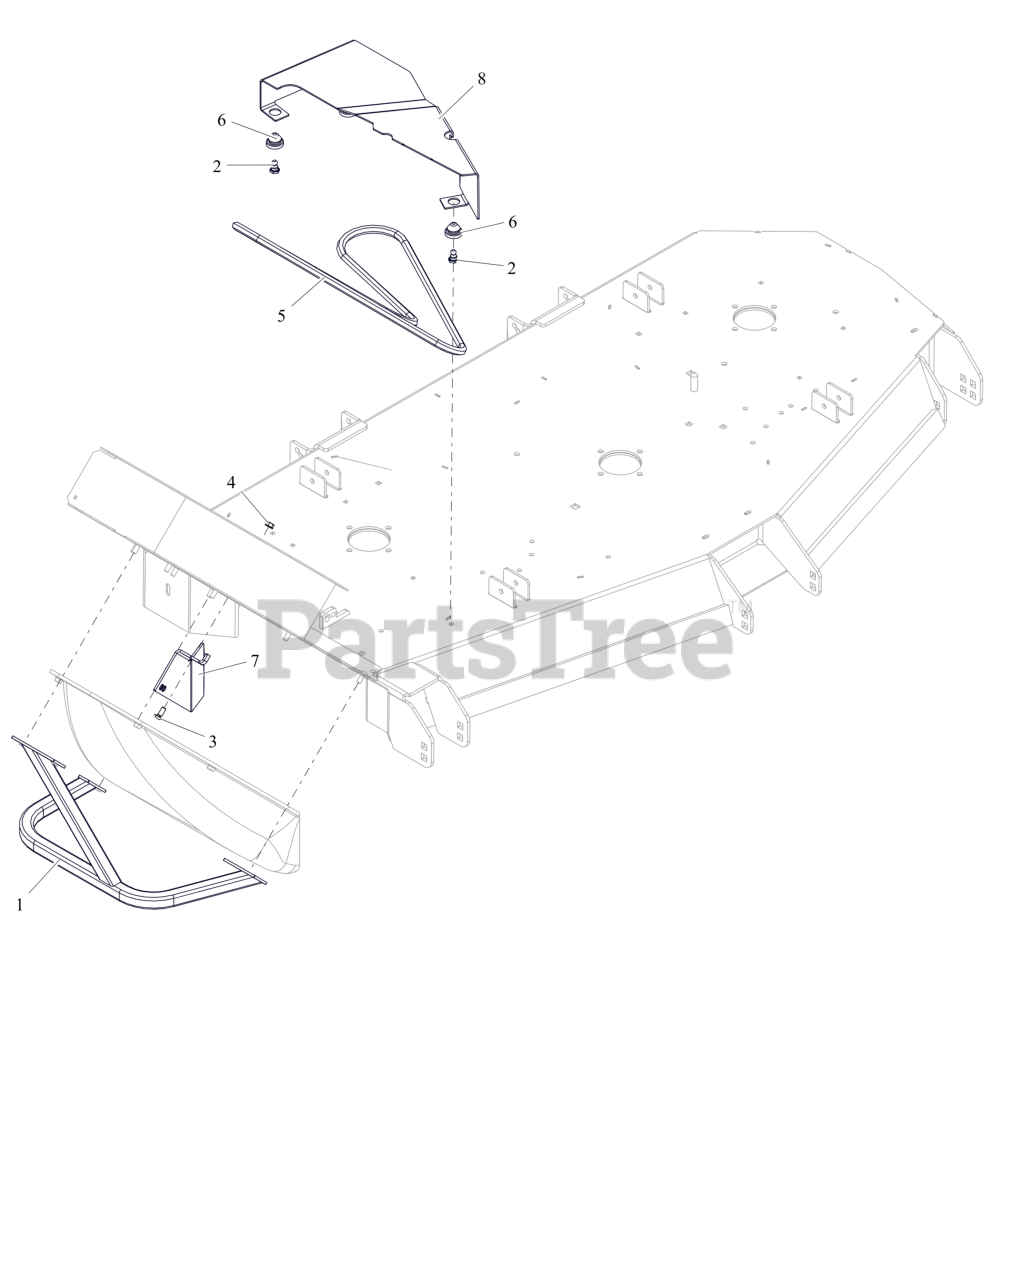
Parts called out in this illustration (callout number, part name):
1	WLDMT, BLOWER GUARD (BLACK)
2	STUD, BALL FEMALE .250-20 THREAD
3	BLT, RHSSN.31-18X.750 G5 ZCC
4	NUT,LK-CTR-FLG .31-18 GF ZCC
5	HEX BELT, HAA SECTION
6	COUPLING, RUBBER PUSH-IN
7	BRKT, PT600 60" BAGGER DISCH (BLACK)
8	GUARD, RH BLOWER DECK BELT (BLACK)
